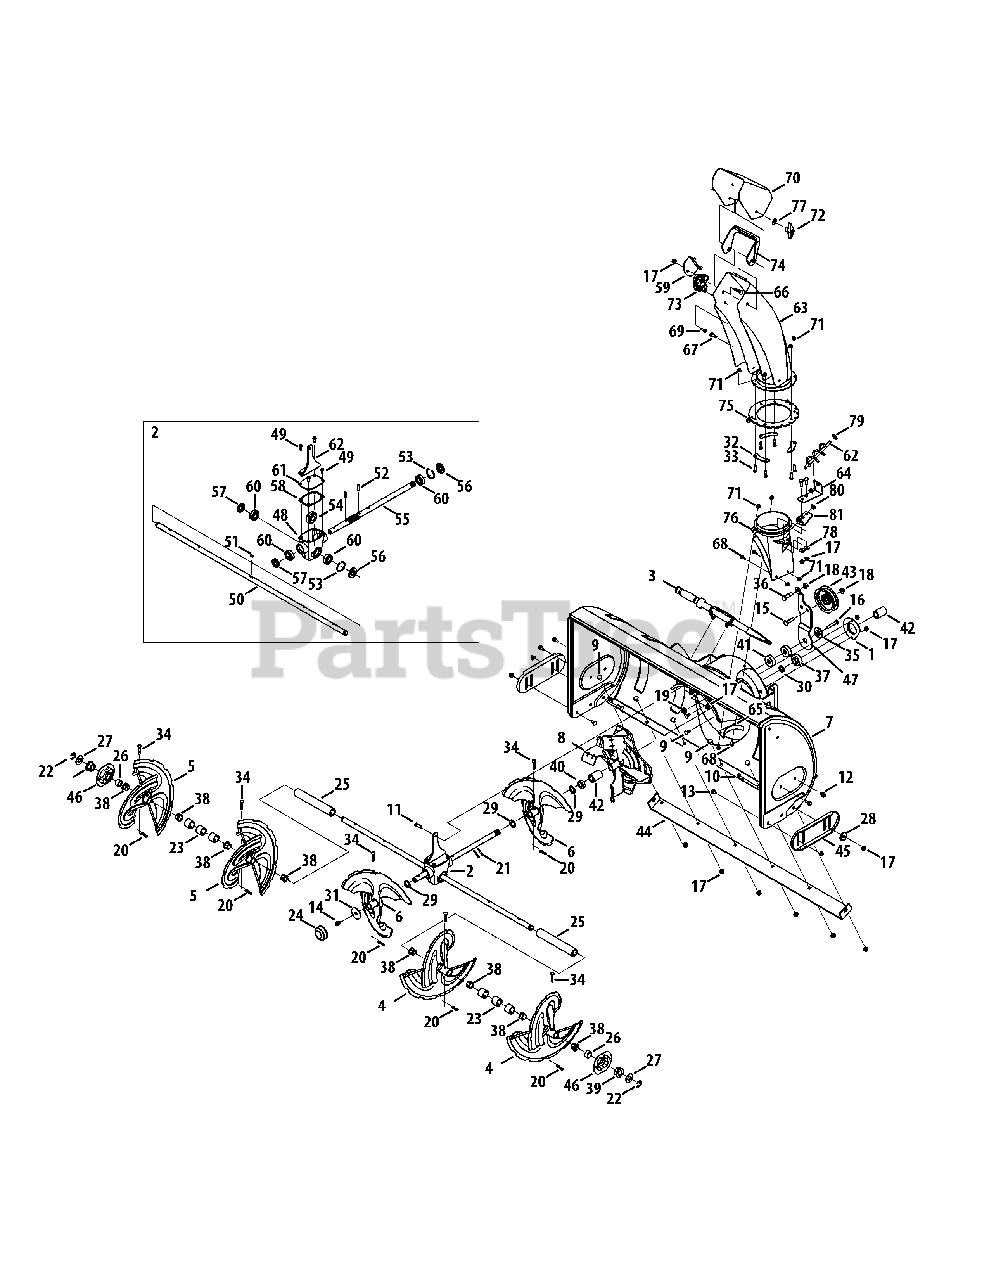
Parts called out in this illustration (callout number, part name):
1	Housing, Bearing, 1.85 ID
2	Gearbox Assembly, Auger, 42"
3	Cleanout Tool Mount
3	Cleanout Tool
4	Spiral Assembly, LH
5	Sipral Assembly, RH
6	Accelerator Assembly
7	Housing, Auger, 42" w/ Baffle
8	Impeller Assembly, 12" Dia
9	Bolt, Carriage, 5/16-18, .62, Gr5
10	Screw, Carriage, 5/16-18, 1.00
11	Hex Screw, 5/16-18, 1.00, Gr5, Std
12	Screw, Self-tapping, 5/16-18, .750
13	Bolt, Carriage, 5/16-18, .750
14	Screw, Self-tapping, 5/16-18, .500
15	Screw, Carriage, 3/8-16, 1.75, Gr5
16	Hex Screw, 3/8-16, 2.00, Gr5, Std
17	Nut, Flange Lock, 5/16-18, Nylon
18	Nut, Flange Lock, 3/8-16, Grf, Nylon
19	Nut, Flange Lock, 3/8-16, Grf
20	Pin, Cotter, bow-Tie
21	Spring, Pin, .250 Dia x 1.50 Spiral
22	Ring, E Type, .750
23	Spacer, 1.25Od x .75Id x 1.00 Lg
24	Cap, Shaft
25	Spacer, 1.25 OD x .75 ID x 7.805 Lg
26	Sleeve, .758 X 1.00 x .555
27	Washer, Flat, .76 x 1.49 x .06, Ht
28	Washer, Flat, .344 x 1.125 x .12
29	Washer, Flat, .793 x 1.24 x .06, Ht
30	Washer, Flat, .75 x 1.13 x .10
31	Washer, Flat, .406 x 1.92 x .060
32	Chute, Flange Keeper
33	SCREW 1/4-20 X1.00 GR5
34	Pin, Shear, .25X1.50, Gr2
35	Spacer, Shoulder, .8840 x .190
36	Screw, Shoulder, .5 x .875 x 3/18-16
37	Bearing, Ball, .75 ID x 1.85 OD
38	Bush, Flange, .800 ID x .910 OD
39	Bearing, Hex Flange x .75 ID
40	Spacer, .766 ID x 1.25 OD x .415
41	Spacer, .385Id x 1.75 OD x .585
42	Spacer, .76Id x 1.25 OD x 1.81 Lg
43	Pulley, Idler, 3.50 Dia.
44	Bracket, Skid Plate, 42"
45	Slide Shoe, Steel
46	Housing, Bearing, 1.1605" Hex
47	Bracket, Idler, Pivot
48	Housing, Auger, 500
49	Screw, Self-tapping, 1/4-20, 0.75
50	Axle, Auger, .75 OD x 41.62 Lg
51	Key, Hi-Pro 3/16 x 5/8
52	Pin, Roll, .25 x 1.00
53	Ring, Retaining
54	Gear, Worm, 20T
55	Shaft, Worm .75 OD
56	Seal, .75 x 40Mm x .25
57	Seal, .75 x 1.375 x .25
58	Gskt, Cover, Gearbox
59	Bracket, Cable
60	Bearing, Ball, .750X40x12
61	Cover, Gearbox, 500
62	Bracket, Support, Gearbox
62	CHUTE CRANK ASSEMBLY
63	Chute Assembly, Steel 5.0"
64	Bracket, Chute, Crank
65	Reinforcment, Chute, 5.0
66	Bolt, Carriage, 5/16-18, 1.50, Gr2
67	Screw, Carriage, Spl, 5/16-18, 1.00
68	Screw, Carriage, 1/4-20, .75, Gr5
69	Screw, 1/4-15, 0.750, Hxindwsh
70	Chute, Upper
71	Nut, Flange Lock, 1/4-20, Grf, Nylon
72	Knob Assembly, Wing Nut 5/16-18
73	Guide, Cable, Chute Tilt 1.05"
74	Adapter, Chute, Upper
75	Ring, Chute, 5"
76	Chute, Adapter 5" Dia
77	Washer, Flat, .349X.879X.063
78	Washer, Bell, .340 x .872 x .060
79	Washer, Flat, .406 x .875 x .059
80	Bearing, Flange, Snap .385 ID
81	Bracket, Chute Crank
